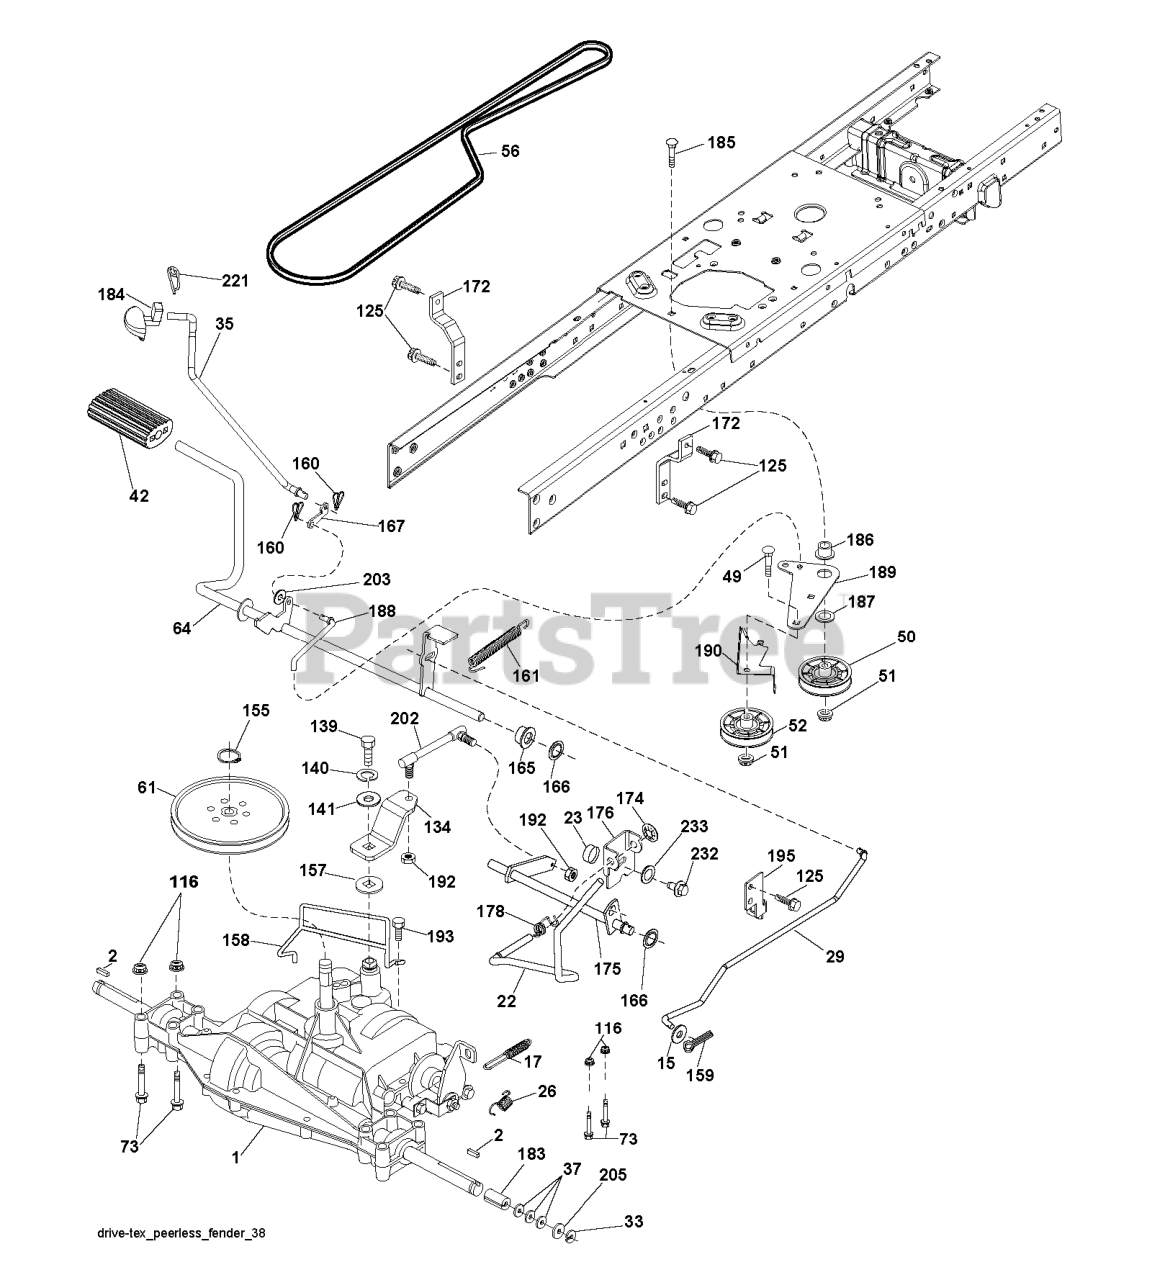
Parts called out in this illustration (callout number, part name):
2	SQUARE KEY
15	WASHER
17	SPRING.BRAKE.PEERLESS.TEX
22	ROD.SHIFT.FENDER.TLT.2006
23	KNOB.DUCKHEAD.1/2
26	SPRING.BRAKE.RTN.GR.DR
29	ROD.BRAKE.PEERLESS
35	ROD.CNTRL.PARK.PREDATOR.LT.TEX
42	PEDAL COVER T
50	IDLER.FLAT.910.OFFSET
51	NUT LOCK FLG 3/8-16 UNC
52	IDLER.V-GROOVE.910.OFFSET
56	V-BELT.TRACTOR.DRIVE.P
61	PULLEY TRANS
64	SHAFT.ASM.PEDAL.BRAKE.
73	BOLT HEX 5/16-18 GR 5
116	NUT LOCK HEX FLANGE 5/16-18
125	SCREW
139	BOLT 1/4-28X3/4
140	LOCKWASHER
155	RETAINING RING LT
157	WASH-SHFT PLT LT
158	KEEPER.PMS.18/20.D4365
159	COTTER PIN
160	RETAINER CLIP
161	SPRING, RETURN LT
165	BUSHING.SHAFT.BRAKE.HAND
166	NUT.PUSH.625
167	LATCH.BRAKE.SPRING
172	STRAP.TRQ.LH.GEAR.DRIV
174	NUT.PUSH.500.2006
175	SHAFT ASM SHIFT
176	ARM.CLEVIS.ROD.SHIFT
178	SPRING.SHIFT.GT2006
183	SPACER AXLE
184	HANDLE PARKING BRAKE
186	SPACER.RETAINER
187	WASHER 12/32X2X10GA
188	RP.LINK.CLUTCH.GROUND.DRIVE
189	BELLCRANK.GROUND.DRIVE.TEX.
190	KEEPER.BELLCRANK.DRIVE
192	NUT LOCK CENTER 1/4 -28 FNTHD
193	SCREW 5/16"
195	BRKT.ROD.BRAKE.PEERLES
202	LINK.SHIFT.PMST.18" (SPG1286)
203	WASHER
221	RETAINER.SPRING.CLIP.H
232	BOLT FIN HEX 7/16-14 X 1
233	WASHER SERRATED
